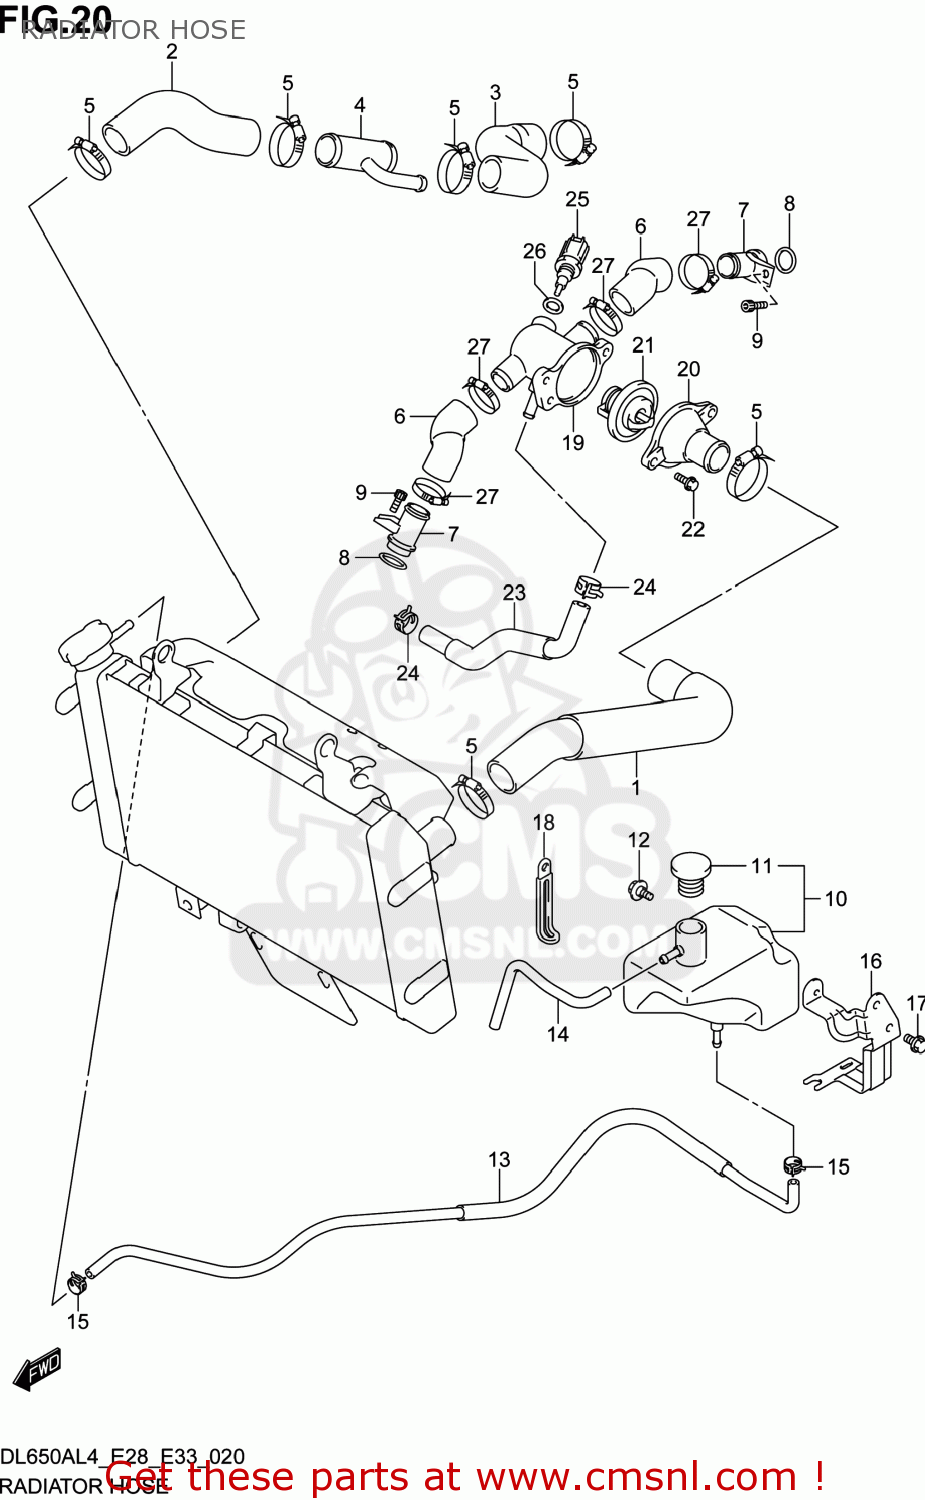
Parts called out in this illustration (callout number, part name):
1	HOSE,RADIATOR INLET
2	HOSE,RADIATOR OUTLET NO.1
3	HOSE,RADIATOR OUTLET NO.2
4	UNION,WATER HOSE THREE WAY
5	CLAMP
6	HOSE,CONNECTOR INLET
7	UNION,CONNECTOR HOSE
8	O RING(D:3.2,ID:17.8)
9	BOLT
10	TANK ASSY,RESERVOIR
11	CAP,RESERVOIR TANK
12	BOLT(6X12)
13	HOSE SET,RESERVOIR TANK INLET
14	HOSE,RESERVOIR TANK OVFL
15	CLIP
16	BRACKET,RESERVOIR TANK
17	BOLT
18	CLAMP(L:45)
19	CONNECTOR,THERMOSTAT INLET
20	CAP,THERMOSTAT CONNECTOR
21	THERMOSTAT,WATER
22	BOLT
23	HOSE,CONNECTOR TO WATER PUMP
24	CLAMP
25	SENSOR,TEMP
26	GASKET(12X17X1) (NAS)
27	CLAMP
